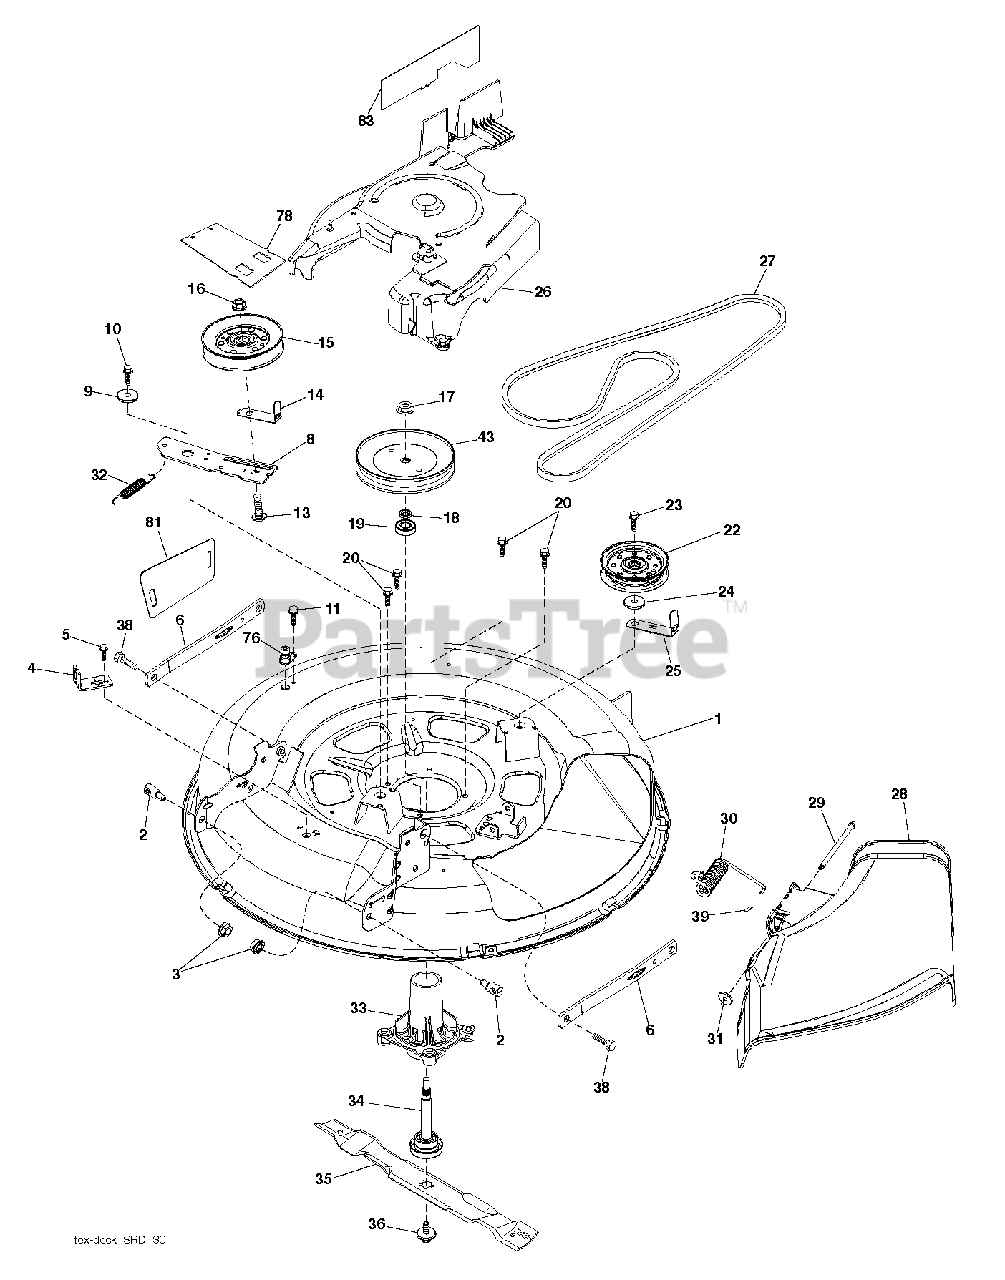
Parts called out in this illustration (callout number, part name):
2	STUD.FASTNER.W/ANTI-ROTATE
3	NUT LOCK HEX FLANGE 5/16-18
5	BOLT.5/16HEX.WHS.HD
6	ARMS.SUSP.MOWER.REAR.SRD
9	SPACER.RETAINER
10	SCREW 3/8-16X1
11	SCREW.1/4-20X5/8
13	BOLT.3/8-16X1.50
14	KEEPER, BELT IDLER
15	PULLEY.IDLER.4.25
16	NUT LOCK FLG 3/8-16 UNC
17	NUT.FLANGE.LOCK.TOP
18	WASHER.SPACER.MANDREL
20	SCREW, WASHER HEAD
22	PULLEY.IDLER.FLAT.UNPLATED
23	SCREW LT
27	V-BELT.DRIVE.MOWER.30"
28	SHIELD.DEFLECT.MWR.30S.BLACK
30	SPRING.TORSION.DEFLECT
31	NUT PUSH M
32	SPRING.MOWER.DRIVE.ELECTRIC
33	HOUSING MANDREL
34	SHAFT.ASM.MDRL.N/GREASE.38
35	BLADE, MULCH.LRV30
36	BOLT.WASHER.ASM.7/16-2
38	BOLT.SHOULDER
39	CAP-SLEEVE LT
43	PULLEY, MANDREL 6.5 PD
76	PORT.WASHOUT
